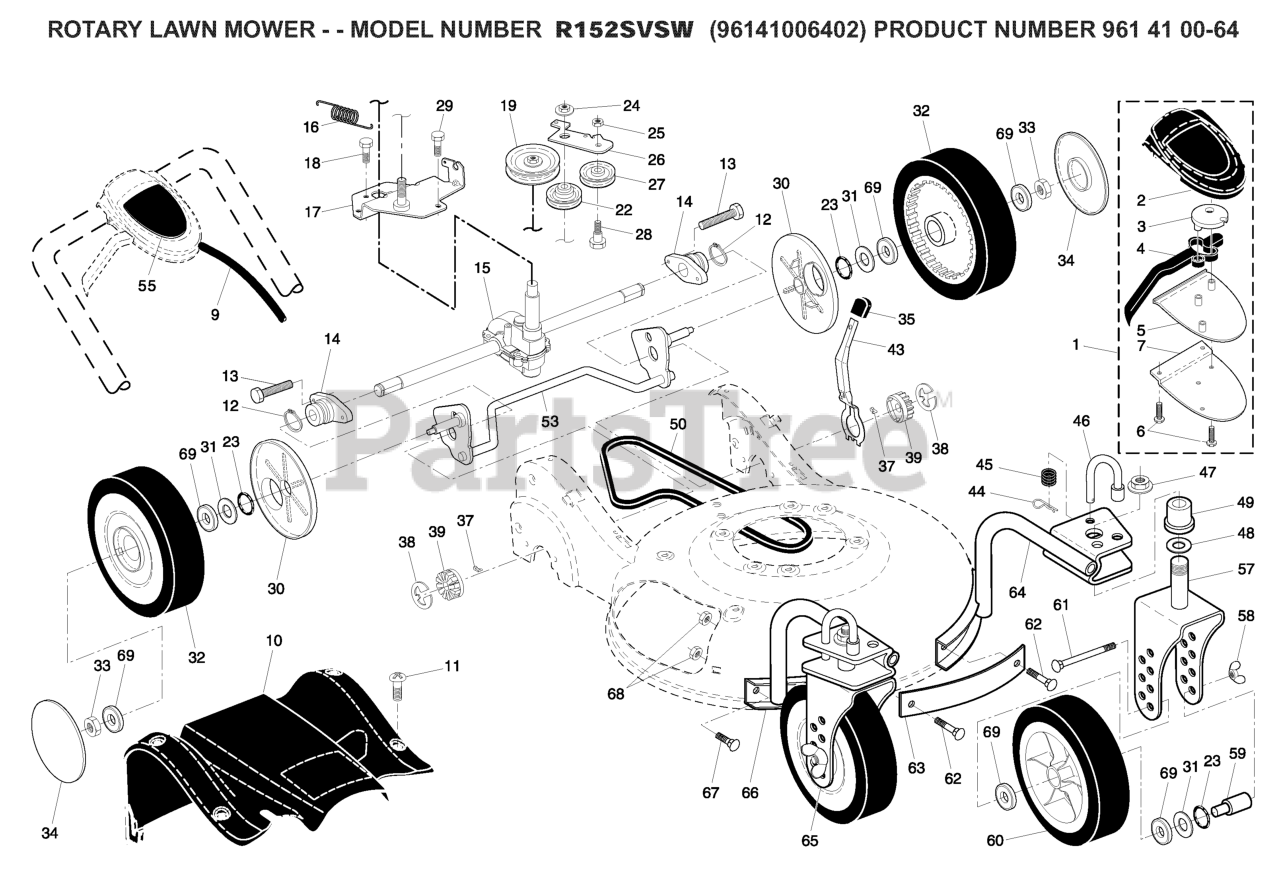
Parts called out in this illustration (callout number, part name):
1	CONTROL.DR.HV.RWGD.GRY/BLU
2	COVER TOP AUTO WALK CONTROL
3	PULLEY.CAM.DRIVE.CONTROL.HV
4	LEVER
5	COVER BOTTOM AUTO WLK CONTROL
6	SCREW, PHILLIPS HEAD 10 X 5/8
7	BRACKET.DRIVE.CONTROL.MOUNT.BL
9	ASM.CABLE.
10	COVER.DRIVE.REAR.21.HV.GRAY
12	RETAINING RING (2 2)(3 2)
13	HINGE SCREW
14	BEARING / AXLE SUPPORT
15	TRANSMISSION.21.RWGD.HV
17	BRACKET, GEAR CASE / DRIVE
19	RP PULLEY.DRIVE.EZ
22	PULLEY.IDLER.V-BELT
23	O-RING
24	NUT.HEX.FLANGE.3/8-16.LOCKNUT
25	NUT.CENTERLOCK.5/16-
26	ARM.IDLER.BZP
27	IDLER PULLEY
28	SHOULDER BOLT
29	SCREW 14-20 X 5/8
30	DUST COVER, WHEEL
31	WASHER.FLAT.1/2
32	WHEEL.9X2.25.LP.TIGER.BLACK
33	NUT.HEX.FLANGE.3/8-16.LO(3 2)
34	HUBCAP.WHEEL.5.SPOKE.SILVER
35	KNOB.SELECTOR.SPRG.H-GRY (2 2)
37	PAWL, DRIVE
38	E-RING 7/16 RE
39	PINION.14.TEETH.FGD
43	LEVER, SELECTOR, HEIGHT, REAR
44	SPRING RETAINER
48	WASHER.FLAT.1/2
50	BELT, DRIVE
53	SHAFT.ASM.REAR.TORQUE.HV.BZP
55	DECAL, DRIVE
57	BRACKET.WHEEL.ASM.LT.CASTER.OR
58	NUT.WING.5/16-18.YELLOW
60	WHEEL.9X2.25.LP.TIGER.SILVER
61	CARRIAGE BOLT
63	STRAP.FRONT.CASTER.ORANGE
64	SUPPORT.TUBE.ASM.LT
65	BRACKET.WHEEL.ASM.RIGHT.ORANGE
66	SUPPORT.TUBE.ASM.RT
68	NUT
69	BEARING.8".WHEEL
